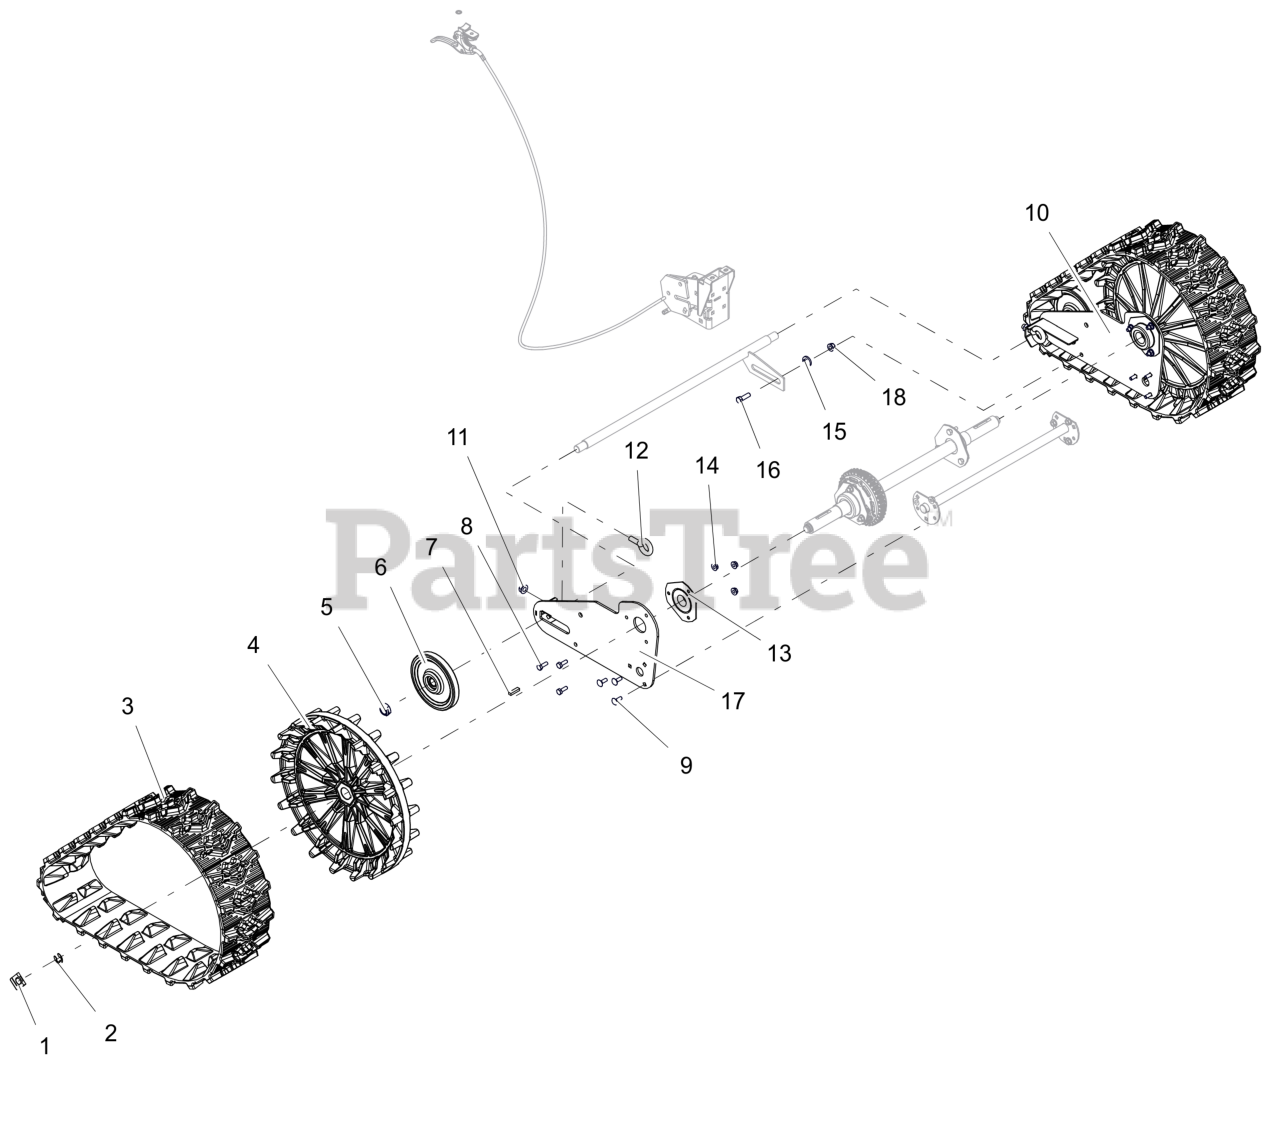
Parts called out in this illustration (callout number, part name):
1	CLIP, SNAP .625 DIA
2	RG-RTNG-EXT .625X.042
3	TRACK, RUBBER - 22 PITCHES
4	SPROCKET, LARGE TRACK DRIVE
5	NUT, NYL LK .625-18 ZCC
6	WHEEL, BOGIE - SINGLE BEARING
7	KEY-RECT .25X.188X1.00
8	BLT, HEX .25-20X.75 G5 ZCC
9	BLT, RHSN .25-20X.750 G5 ZCC
10	PLATE, SIDE-BWT LH WLDMT
11	NUT-LK-CTR-FLG .375-16 GF ZCC
12	BLT-EYE .375-16X.880 YWZC
13	BRG-FLG 1.003/1.000 3 BOLT
14	NUT-LK-TOP-FLG .250-20 GF ZCC
15	BSHG-FLG .325X.499X.3X.875
16	BLT,HEX .31-18X1.00 G5 ZCC
17	PLATE, SIDE-BWT RH WLDMT
18	NUT-LK-TOP-FLG .312-18 GF ZCC
